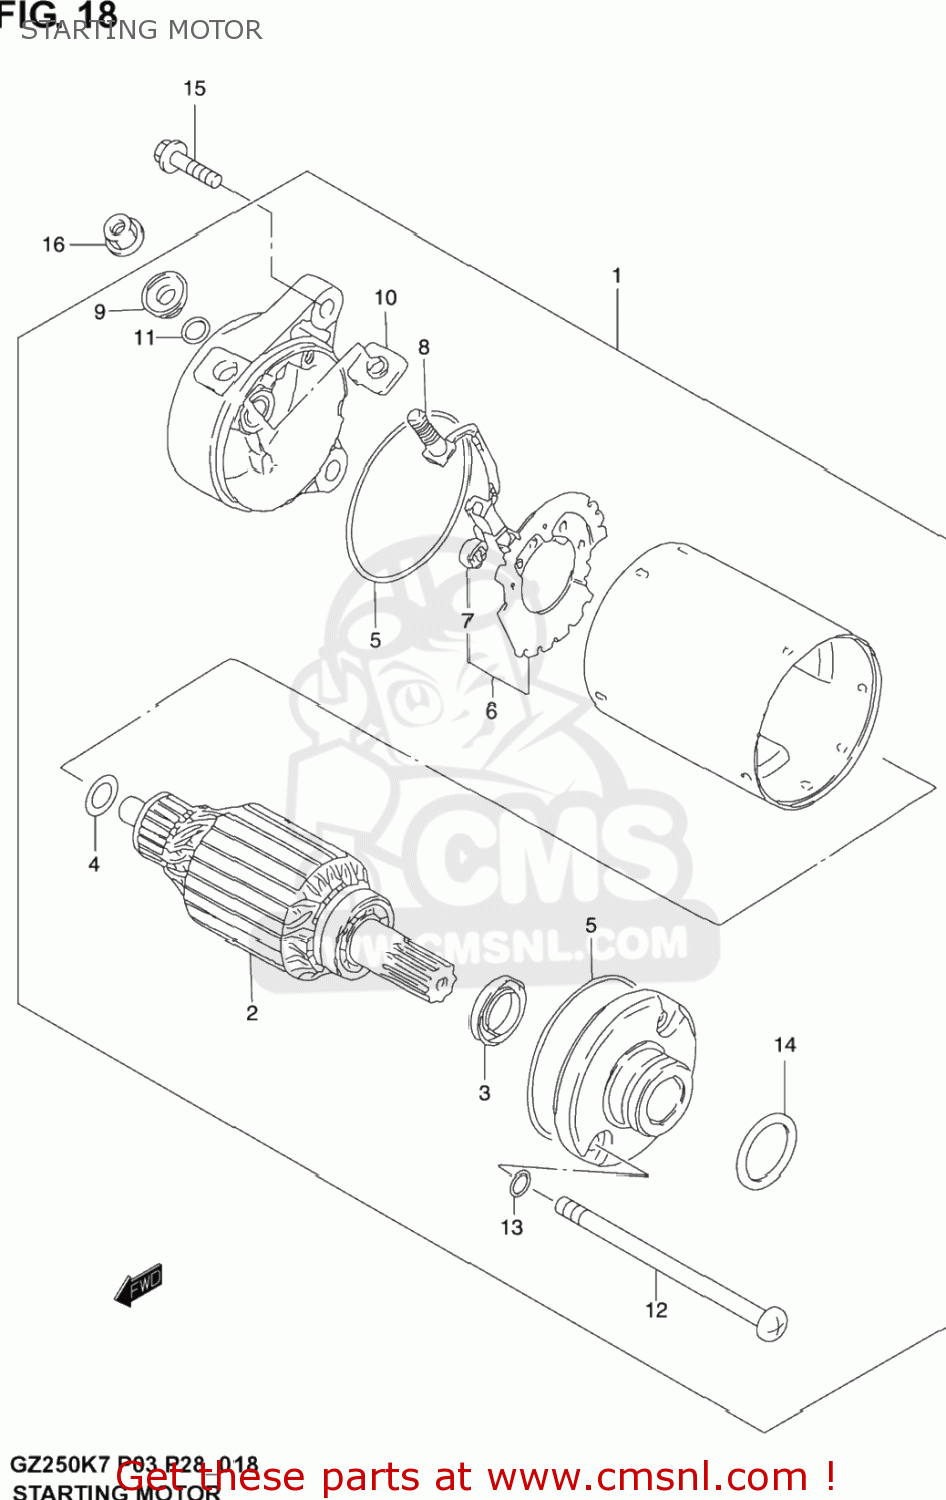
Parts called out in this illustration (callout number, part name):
1	MOTOR ASSY,STARTING
2	ARMATURE
3	SEAL,OIL
4	SHIM SET,STARTING MOTOR
5	O RING
6	HOLDER,BRUSH
7	SPRING
8	BRUSH SUB ASSY,STARTING MOTOR
9	BUSHING
10	BUSH,B
11	O RING
12	BOLT
13	O RING
14	O RING(D:3,ID:24.5)
15	SCREW
16	NUT
